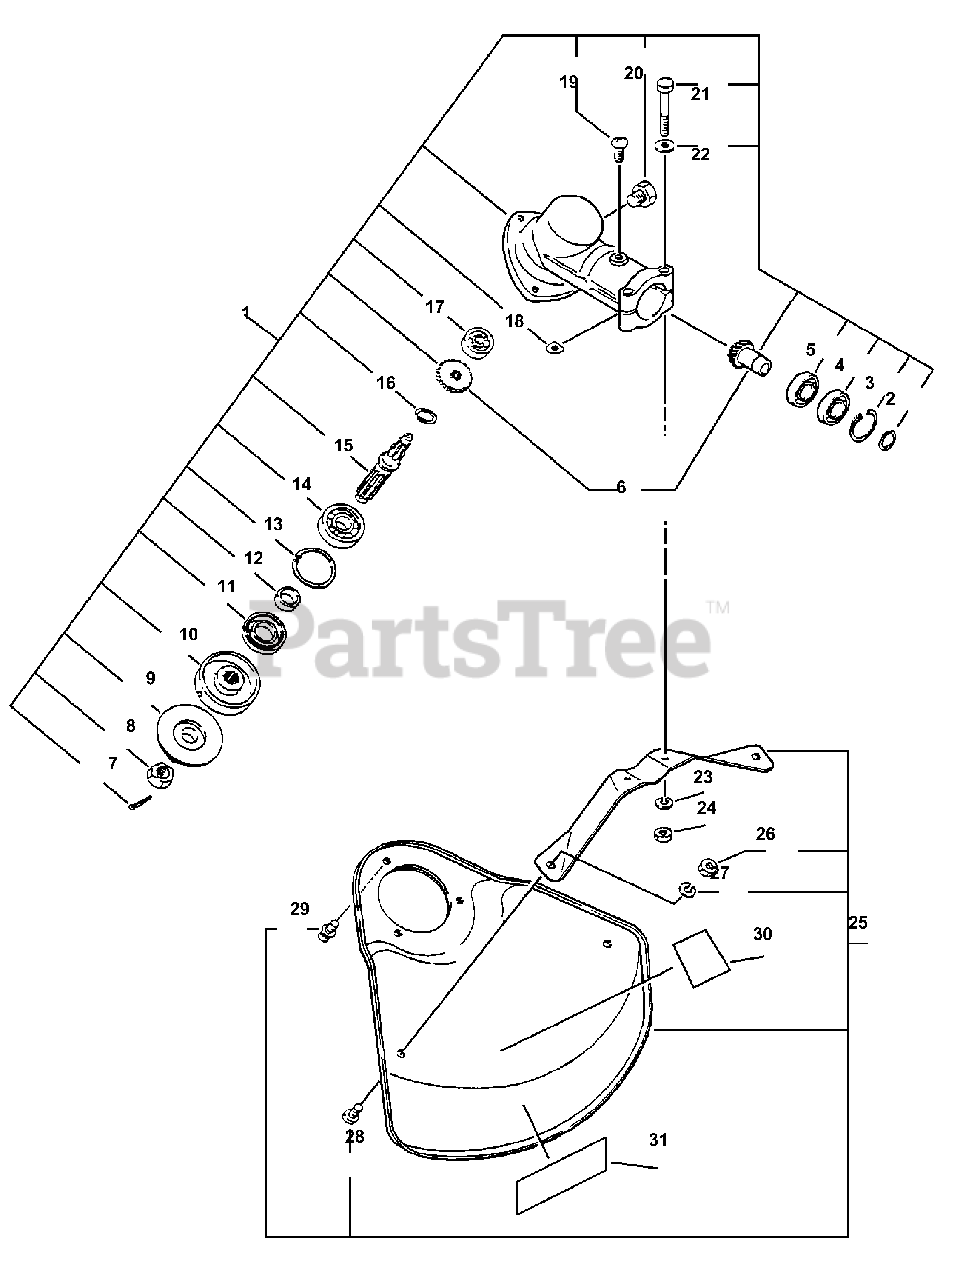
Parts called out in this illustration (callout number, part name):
1	GEAR CASE ASSY
2	RING, SNAP Ø10
3	RING, SNAP Ø22
4	BEARING, BALL 6900Z
5	BEARING, BALL 6900
6	GEAR SET
7	PIN, COTTER 2×22
8	NUT 10
9	PLATE, ADAPTOR - LOWER
10	PLATE, ADAPTER - UPPER
11	SEAL, OIL 22
12	SPACER 11.8×15×9
13	RING, SNAP Ø32
14	BEARING, BALL - 6201 C3
15	SHAFT, GEAR
16	RING, SNAP Ø12
17	BEARING, BALL 609
18	D-WASHER
19	SCREW 5×10
20	BOLT 8×8 SP
21	BOLT 5×35 SP
22	WASHER, FLAT 5.5×10×0.8
23	WASHER, SPRING 5
24	NUT M5
25	SHIELD ASSY
26	NUT M5
27	WASHER, SPRING 5
28	SCREW 5×8
29	SCREW 5×10
30	LABEL, CAUTION
31	LABEL, ECHO
